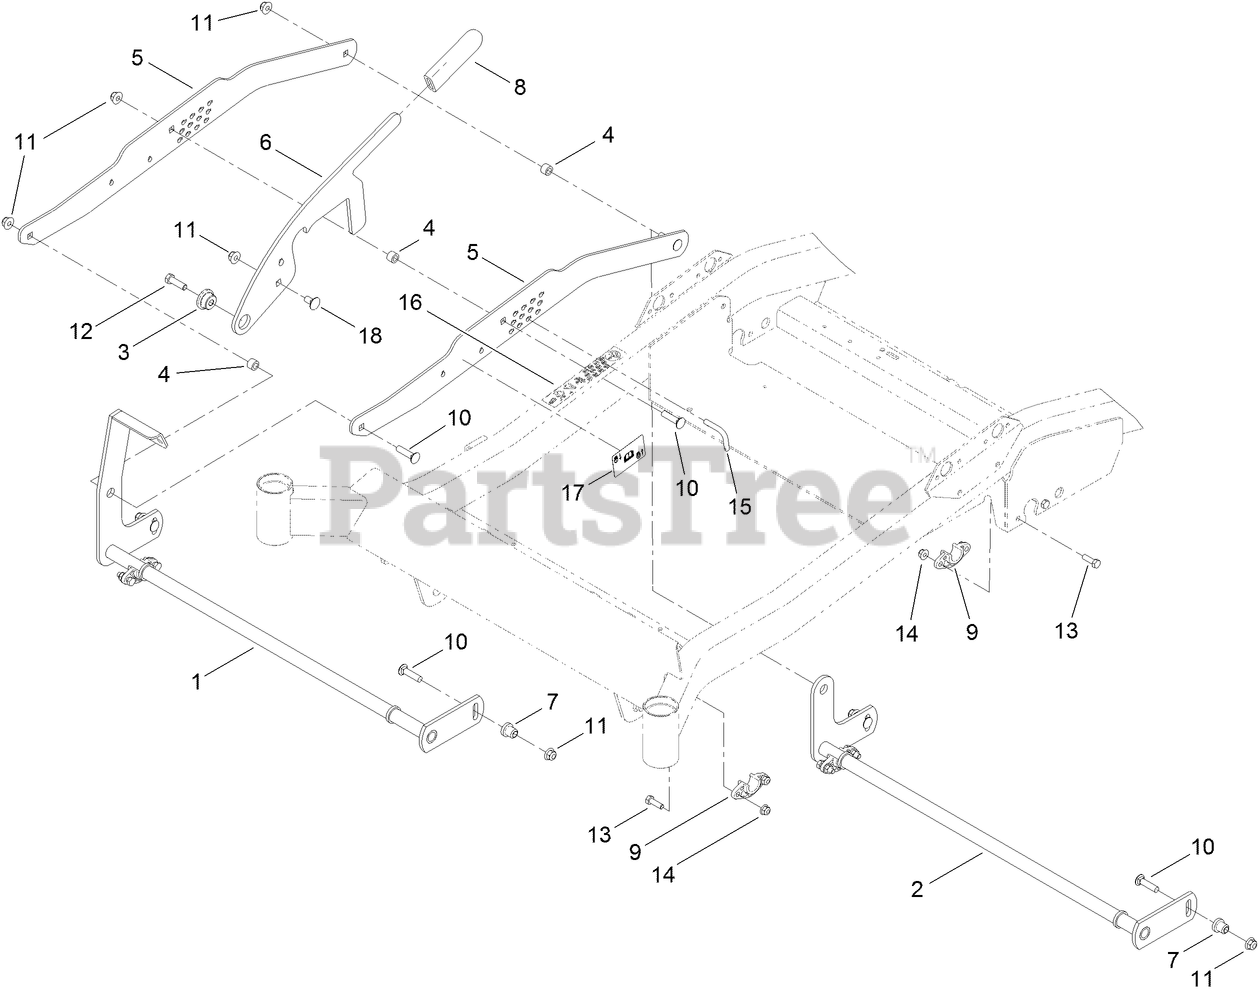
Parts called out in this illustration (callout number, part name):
1	PIVOT-FRONT
2	PIVOT-REAR
3	BUSHING-MOUNT, HOC
4	SPACER
5	PLATE-LIFT, FOOT
6	PLATE-STOP, HOC
7	BUSHING-PULLEY
8	GRIP-LEVER
9	BUSHING-FLANGE
10	SCREW-CARR
11	NUT-HF, NI
12	SCREW-HH
13	SCREW-HH
14	NUT-HF, NI
15	PIN-KEYED
16	DECAL-HOC
17	DECAL-LOCK, DECK
18	SCREW-CARR
